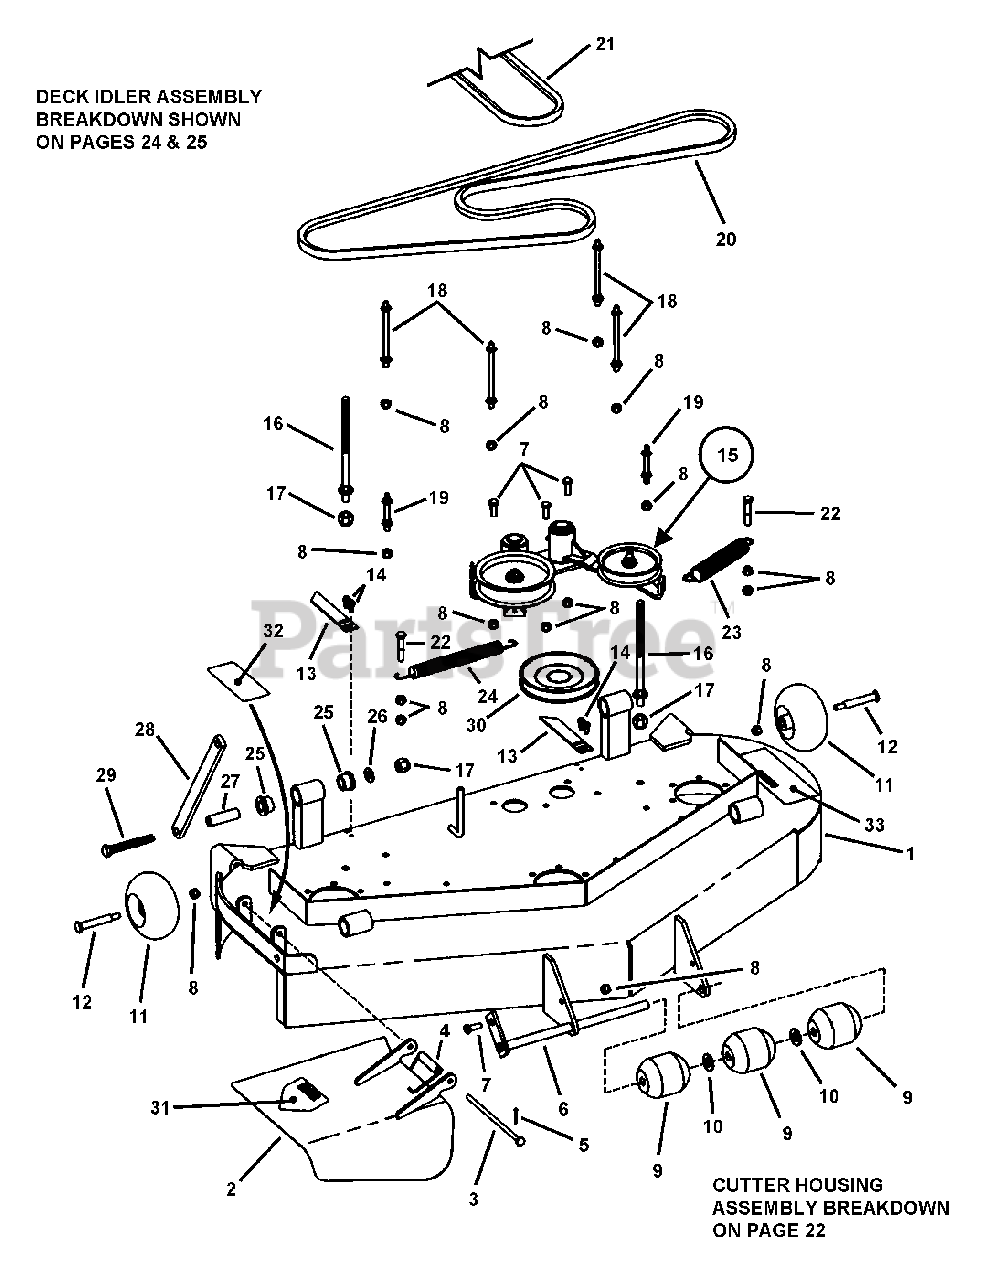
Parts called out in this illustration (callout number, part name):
1	WELDMENT, 48" Deck
2	DEFLECTOR, 48" Deck (Weldment)
3	PIN, Chute Hinge
4	SPRING, Chute
5	PIN, 3/32 x 1" Cotter
6	PIVOT, Roller Pin
7	BOLT, 3/8-16 X 1" GD5 CZ
8	NUT, 3/8-16 HEX NYLON LOCK
9	ROLLER, Low Density Polyethylene
10	WASHER, 5/8" Flat
11	WHEEL, Gage
12	BOLT, 1/2" Diameter Shoulder, 3/8-16 Thread
13	POINTER, Height-of-Cut
14	SCREW, 1/4-20 x 5/8" Hex Washer Self-Tap
15	ASSEMBLY, Idler (48" & 61" Decks)
16	STUD, Lift, 1/2-13 thread (both ends)
17	NUT, 1/2-13 Hex Nyloc
18	STANDOFF, 4-1/2" Long (5/16-18 thread, top end; 3/8-16 thread, bottom end)
19	STANDOFF, 2" Long (5/16-18 thread, top end; (3/8-16 thread, bottom end)
20	V-BELT, 48" Deck Secondary (113" Long)
21	V-BELT, 48" Deck Primary (66" Long)
22	BOLT, 3/8-16 X 2, GD5, CZ
23	SPRING, Idler
24	SPRING, Extension (Primary Idler) (48" Deck)
25	BUSHING, Suspension
26	WASHER, 1/2" Flat
27	SLEEVE, Suspension (All Models)
28	ARM, Suspension 12" Long (48" & 52" Decks)
29	BOLT, 1/2-13 x 3-3/4", Grade 5
30	PULLEY, 5-3/4" (48"/52" Decks)
31	DECAL, Warning (CPSC Cut Finger)
32	DECAL, Warning
33	DECAL, Caution- Operator Instruction
